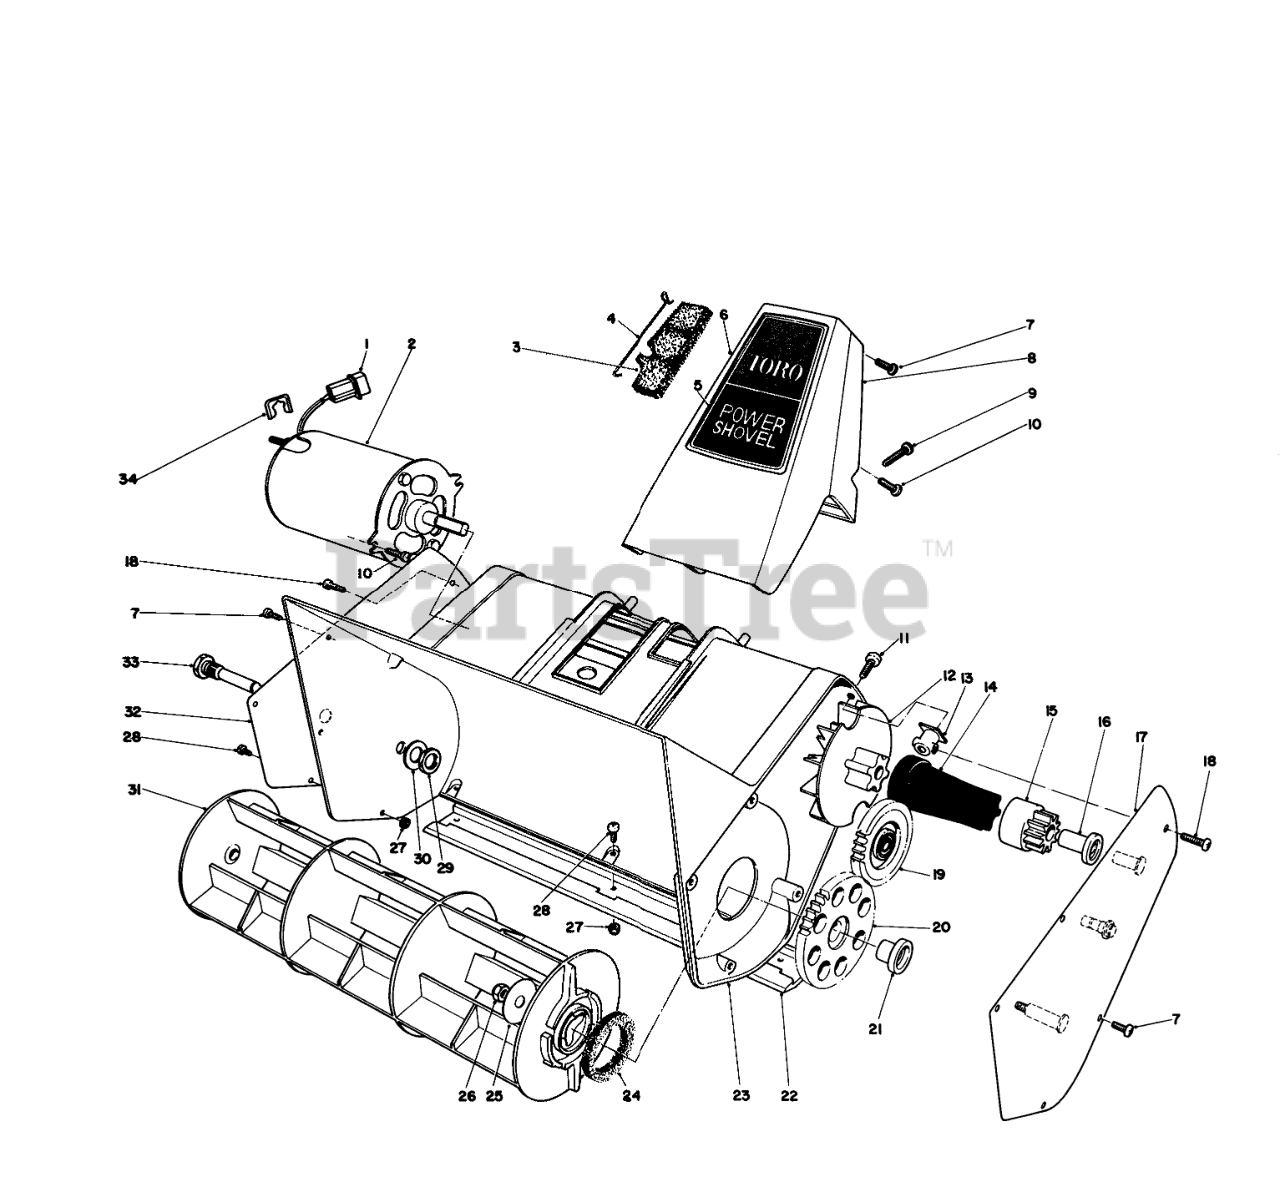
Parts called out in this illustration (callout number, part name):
1	Pin Housing
2	ELEC MOTOR
3	FOAM FILTER
4	RETAINER - FILTER
5	HANDLE SUPT DECAL
6	HANDLE SUPPORT, FRONT
7	SCREW-PPH
8	Handle Support-Back
9	SCREW-PPH
10	SCREW-PPH
11	#10-10X3/4 PLASCREW
12	FAN, POWER SHOVEL
13	MOUNTING BLOCK
14	DRIVE COUPLING
15	Drive Gear (Incl. Ref. #16)
16	BUSHING, DRIVE GEAR
17	Gear Carrier
18	Screw
19	IDLER GEAR ASM
20	Rotor Gear Assembly (Incl. Ref. #21)
21	BUSHING, ROTOR GEAR
22	Scraper
23	H.S. HOUSING-CSA
24	FELT WASHER
25	ROTOR WASHER
26	NUT-LOCK, NI
27	NUT-LOCK
28	SCREW-PPH
29	NUT-LOCK, CONE
30	WASHER-FLAT
31	ROTOR
32	RT. SIDE COVER (RAW)
33	ROTOR PIN
34	Strain Relief
